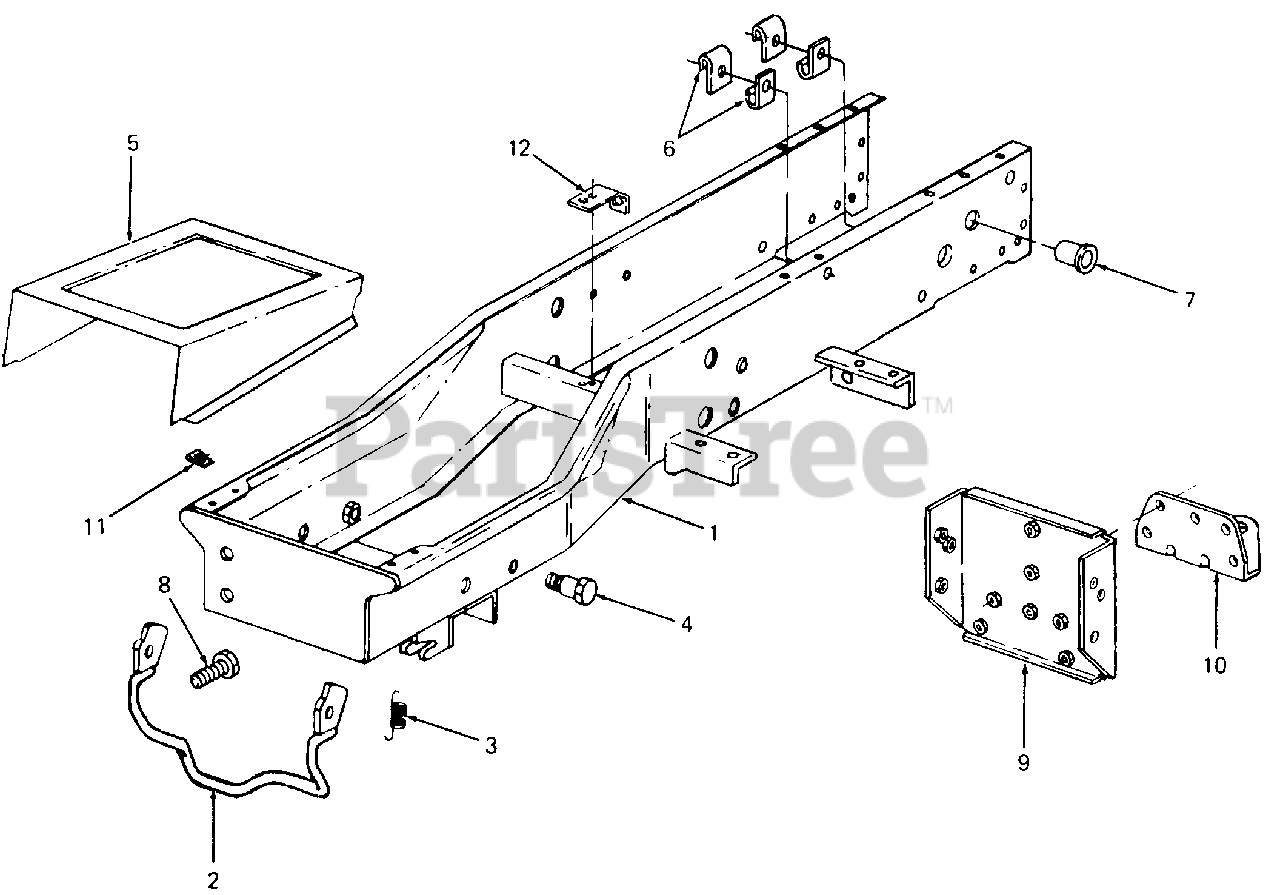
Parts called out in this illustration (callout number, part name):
3	Spring, Latch
4	Bolt, Shoulder
5	Cver, Frame w/Graphic
6	Clip, Cable
7	Bushing, Snap
8	Screw, Adjustment, 1/2-20 x 1.0 Lg GR5
11	Nut, Speed
12	Bracket, Switch
